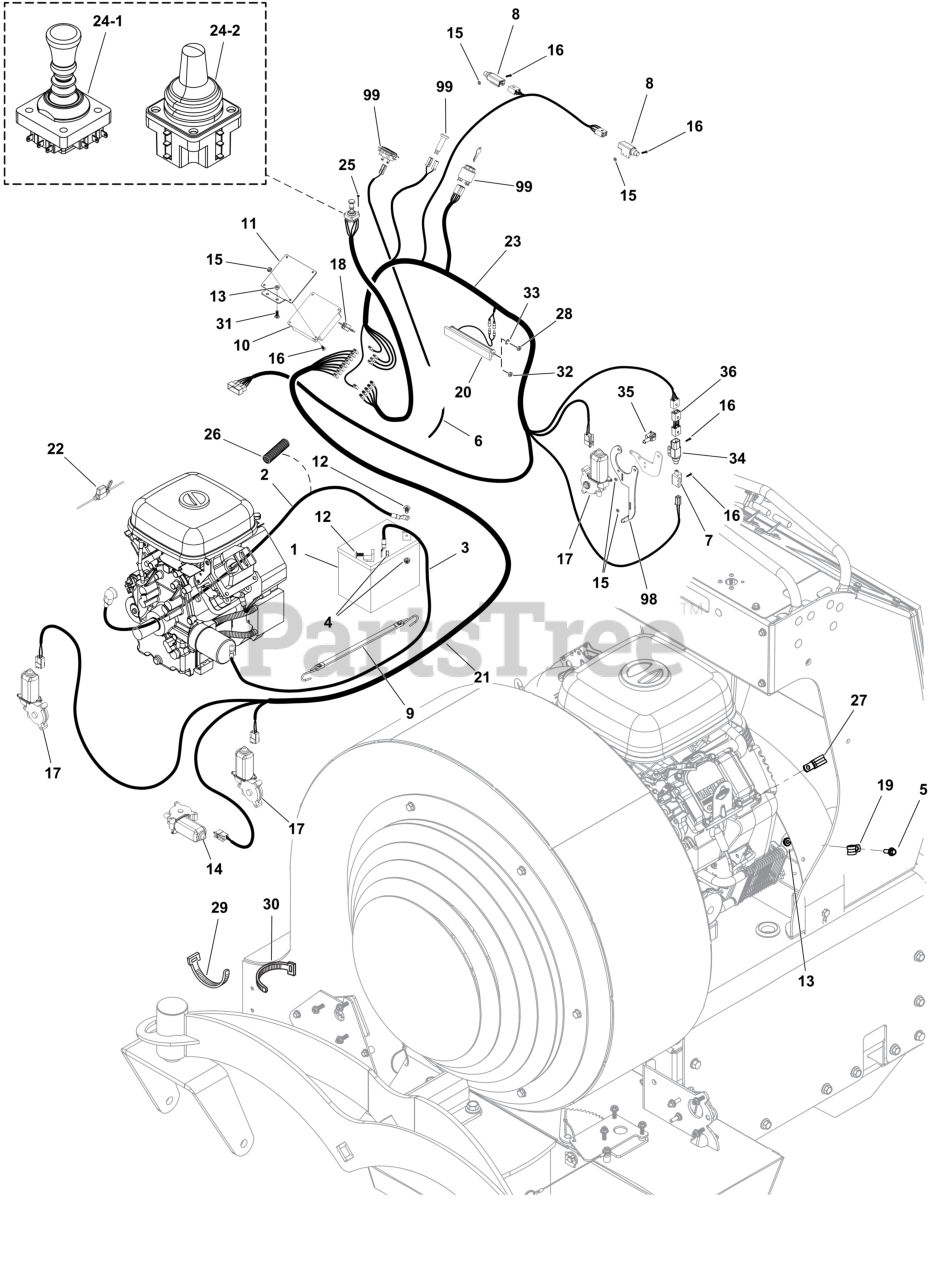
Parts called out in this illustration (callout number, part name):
1	BATTERY
2	CABLE, BATTERY, RED
3	CABLE, BATTERY, BLACK
4	NUT, 5/16-18 HEX SERR
6	HARNESS, WIRING
7	SWITCH, PLUNGER, N.C.
9	STRAP, Battery
10	KIT, RELAY, CONTROL MODULE
12	BOLT, 5/16-18 X 3/4",
15	NUT-HEX & WASHER ASMY
16	SCREW (#10-32 X 3/4, ALLEN, SS)
17	DEFLECTOR, Motor
18	BREAKER, CIRCUIT, 15A
19	CLAMP, VINYL INSULATED, .50
20	HEADLIGHT ASSEMBLY
21	HARNESS, WIRING
22	HOLDER, FUSE
23	HARNESS, WIRING
24-1	KIT, JOYSTICK UPDATE
24-2	KIT, Joystick
25	SCREW (#10-32 X 3/4, ALLEN, SS)
26	WIRE LOOM, 3/8 ID X 17.5 IN
28	NUT, HEX, M5X.8MM, NYLON INSERT
29	TIE WRAP, 11" Long
30	TIE WRAP, 5-1/2" LONG
31	BOLT, 1/4-20X.750, SQ
32	NUT, HEX, M6-1, NYLON INSERT
33	WASHER, 5MM, STAR, CZ
36	WIRE HARNESS, JUMPER, BRAKE SWITCH
98	Refer to: Parking Brake Group
99	Refer to: Instrument Control Panel Group
